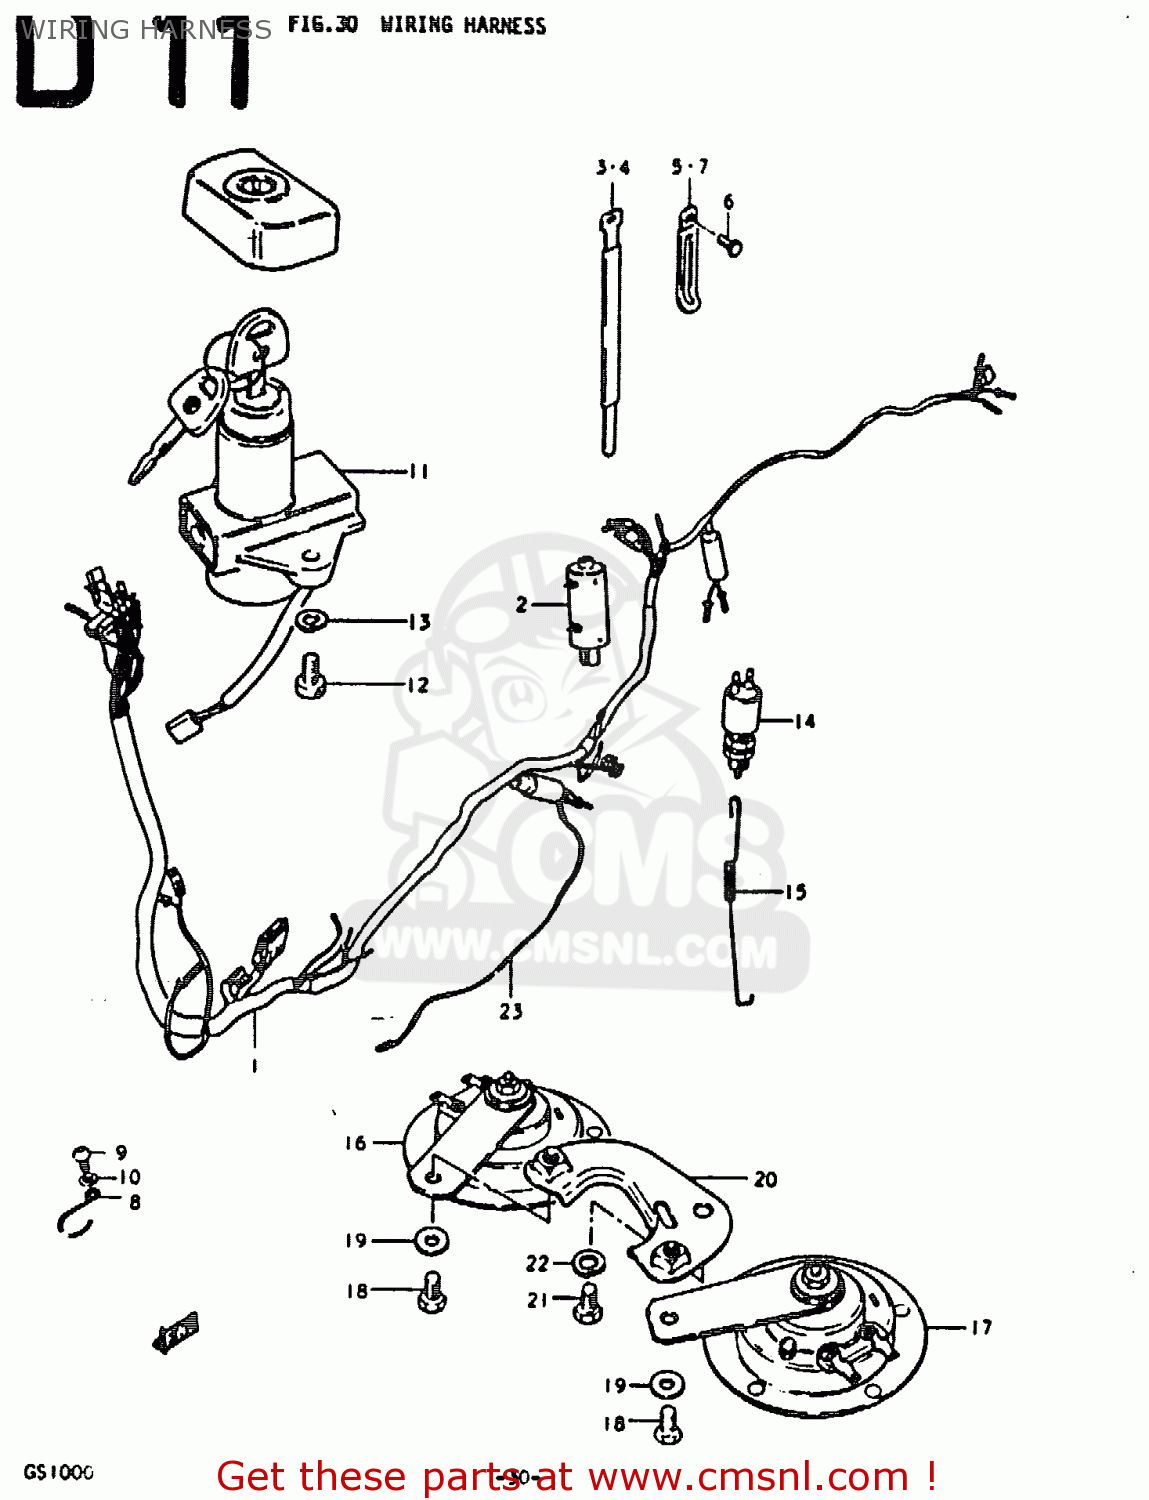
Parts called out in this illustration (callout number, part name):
1	HARNESS,WIRING
2	BOOT,WIRING HARNESS
3	CLAMP(L:120)
4	CLAMP
5	CLAMP
6	BOLT
7	CLAMP
8	GUIDE,WIRING HARNESS
9	SCREW 6X12
10	WASHER 6MM
11	LOCK ASSEMBLY,STEERING
12	BOLT
13	LOCK WASHER
14	SWITCH ASSY,BRAKE LAMP
15	SPRING
16	HORN ASSY
17	HORN ASSEMBLY,HIGH PITCH
18	BOLT 8X12
19	WASHER
20	BRACKET,HORN
21	BOLT
22	LOCK WASHER
23	WIRE
